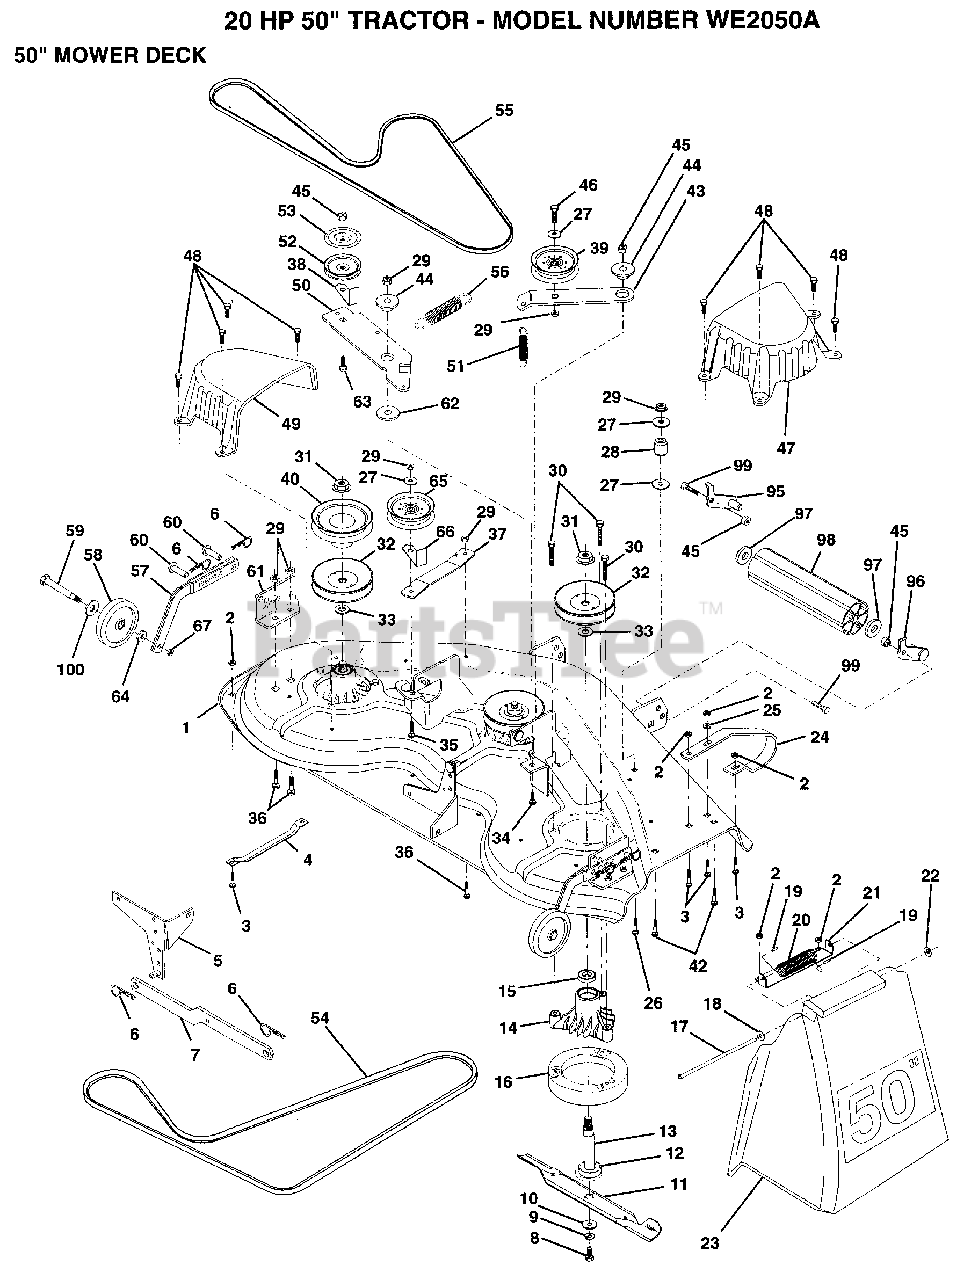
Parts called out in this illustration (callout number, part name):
1	DECK ASM MWR 50VT
2	NUT
4	RUNNER-LH M
5	BRKT.ASM.SW.44/50
8	BLADE BOLT
10	WASHER.HARD.BLADE
11	"BLADE.50"" HD"
12	BEARING.BALL
13	SHAFT.ASM.W/BRNG
14	HOUSING.MAND.44.V
15	BEARING
16	STRIPPER RND MWR
17	ROD-HINGE T
18	WASHER
19	CAP-SLEEVE LT
20	SPRING TORSION
21	BRKT DEFLECTOR
22	NUT PUSH M
23	DEFLECTOR
24	"RUNNER RH 50"" DK"
25	WASHER M
26	BOLT
27	WASHER
29	NUT
33	WASHER
34	BOLT.3/8-14X1.25
35	BOLT
36	BOLT D
37	STIFFENER.ARM.IDL
38	STIFFENER.ARM.IDL
39	FLAT IDLER PULLEY
40	"PULLEY.DRIVEN.44"""
42	BOLT
43	"ARM.IDLER.SEC.44"""
44	SPACER RETAINER
47	"COVER.MAND.RH.44"""
48	SCREW.1/4-20X5/8
49	COVER.MANDREL.LH
50	ARM.IDLER.PRIMARY
51	"SPRING.SEC.44""VEN"
52	PULLEY.IDLER.VGRO
53	SHIELD.IDLER.44.V
54	BELT V PRIM 50
55	BELT.V.GDRIVE.95
56	SPRING.EXT.DECK.
57	BAR.ASM.GUAGE.WHL
58	WHEEL.GAGE.BLK.PL
59	BOLT M
60	PIN.CLEVIS
61	BRACKET.GUAGE.WHL
62	HARDENED WASHER
63	BOLT.3/8-16X1.50
64	WASHER
65	IDLER-FLAT T
67	LOCKNUT
97	WASHER
99	BOLT
100	WASHER
